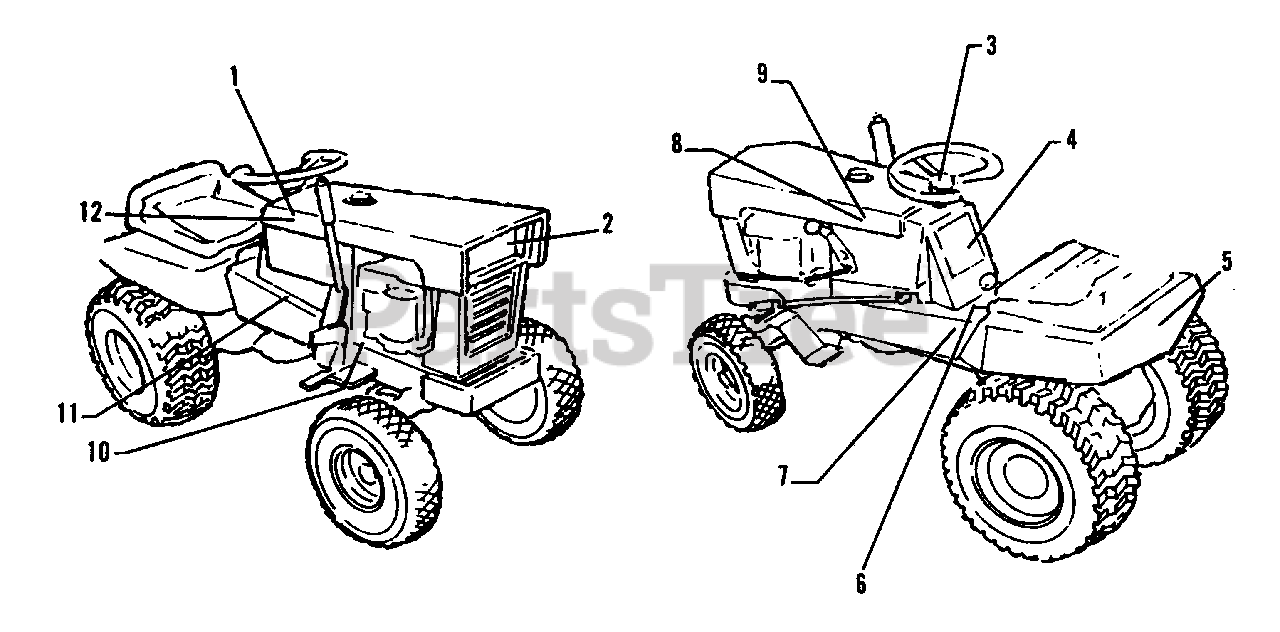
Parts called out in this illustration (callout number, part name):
1	DECAL, R.H., Insert
2	DECAL, Grille
3	DECAL, Steering Wheel
4	DECAL, Dash
5	DECAL, Rear Seat Deck (1690020 & 1690106 Only)
6	DECAL, Safety & Shift Pattern
7	FILM, Brake
8	DECAL, L.H. Insert
9	DECAL, Hood, L.H. (1690019 Only)
9	DECAL, Hood, L.H.
10	DECAL, Clutch
11	FILM, Lift Lever
12	DECAL, Hood, R.H. (1690019 Only)
12	DECAL, Hood, R.H.
